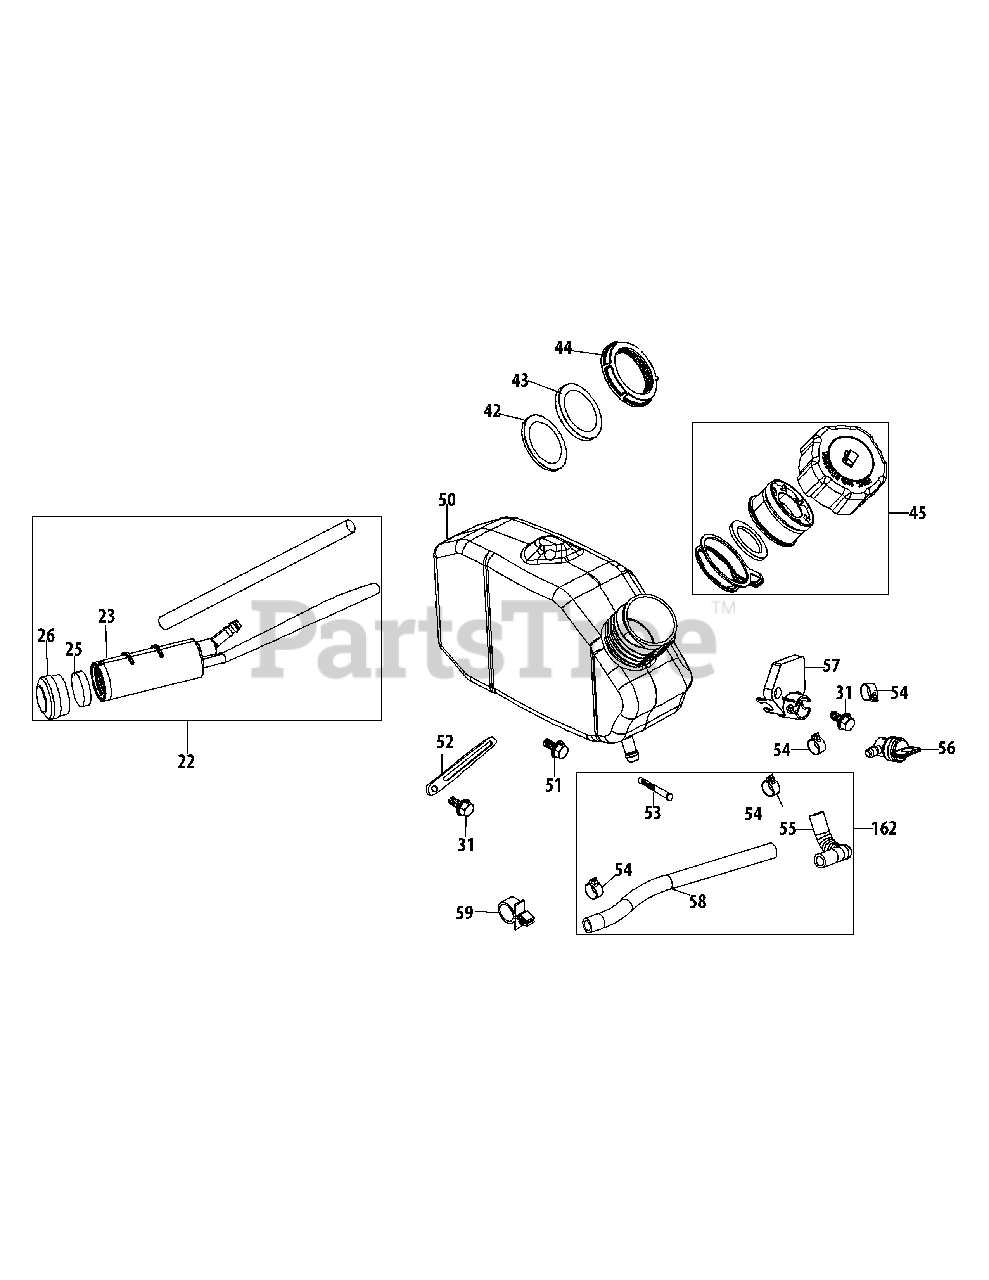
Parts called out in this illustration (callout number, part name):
22	Carbon Canister Assembly
23	Carbon Canister
25	Carbon Canister Filter
26	Carbon Canister Filter Cap
31	Bolt M6×25 Cover Plate
42	Fuel Tank Lower Grommet
43	Fuel Tank Upper Grommet
44	Fuel Tank Nut
45	Fuel Cap Assembly
50	Fuel Tank
51	Bolt M6X12 Multi-Purpose
52	Flexible Clamp, Vent Hose
53	Fuel Filter
54	Fuel Hose Clamp
55	Fuel Hose Carb Section
56	Fuel Shut-Off Valve
57	Fuel Shut-Off Valve Mount
58	Fuel Hose Tank Section
59	Plastic Support Clamp
162	Fuel Line Kit
